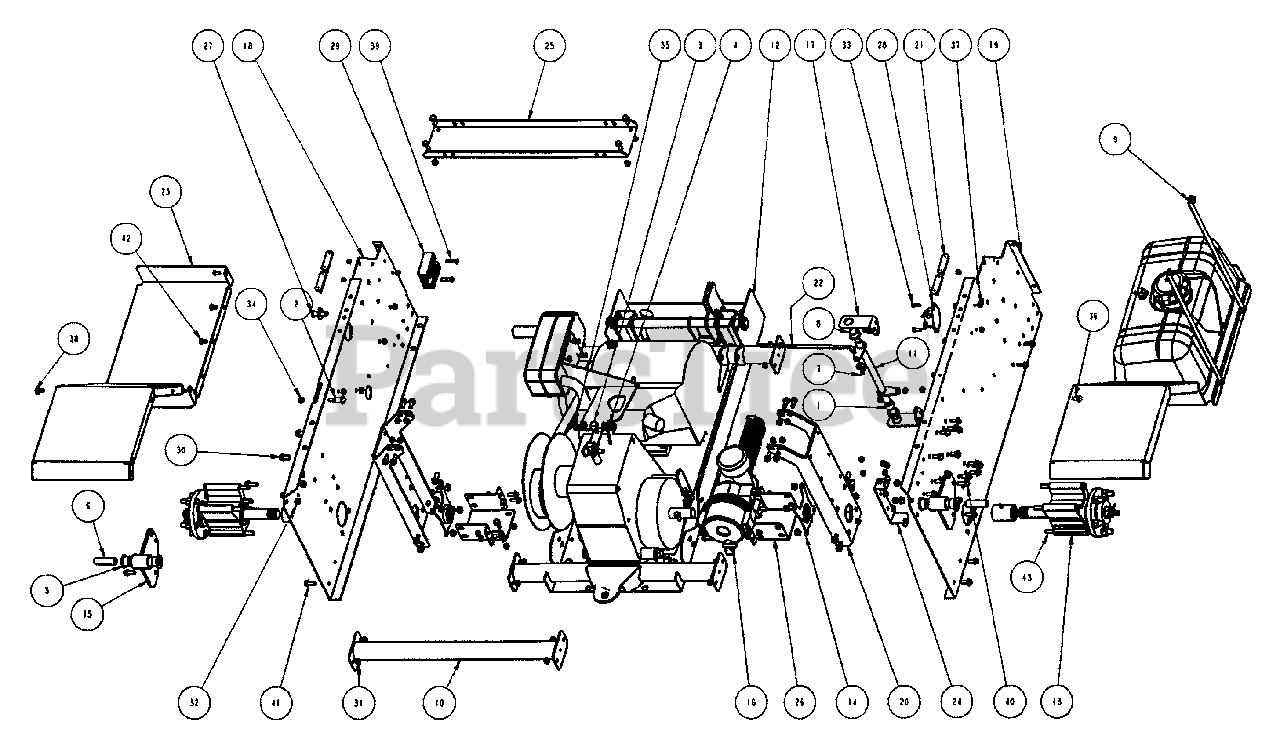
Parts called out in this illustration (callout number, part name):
1	RING, REAR LIFT ARM
2	HSB, 3/8-24 X 1-1/2
3	SWIVEL (3/8" THRU HOLE)
4	FRICTION PACK SPRING
5	BUSHING-SUSPENSION
6	SLEEVE-SUSPENSION
7	5/16 COTTER PIN, SELF LOCKING
8	BEARING, .750 ID
9	See "Fuel Tank Group" illustration and parts list
10	WELDMENT, TUBE SUPPORT
11	WELDMENT, SPEED CONTROL SHAFT
12	GROUP, DRIVE BASE
13	GROUP, CVT AXLE
14	ASSEMBLY, PLATE/SEAL
15	WELDMENT, DUMP BED PIVOT
16	AIR FILTER ASSEMBLY
17	BRKT., SPEED CONTROL X-SHAFT
18	FRAME, LH REAR
19	FRAME, RH REAR
20	STIFFENER, CVT FRAME
21	BUMPER, RUBBER
22	ROD, UPPER NEUTRAL RETURN
23	BRKT., GAS TANK
24	BRKT., AIR CLEANER MOUNTING
25	CHANNEL, FRAME STIFFENER
26	CHANNEL, SUBFRAME CONNECT
27	PIN, BED LATCH STRIKER
28	FUEL PUMP
29	REGULATOR/RECTIFIER, KAWASAKI
30	HWST, 3/8-16 X 3/4
31	HEX NYLON INSERT NUT 5/16-18 YZ
32	HNYL, 3/8-16, YZ
33	HHCS, 1/4-20 X 3/4 GR 5 YZ
34	HEX NYLOCK NUT 3/8-24
35	WASHER, .375 X.875 X.083
36	HFLB 3/8-16 X 3/4-YZ
37	1/4-20 HEX NYLON INSERT NUT
38	HFLB, 5/16-18 X .625-YZ
39	HHCS, 1/4-20 X 1.25 YZ
40	HFLB 3/8-16 X 1.0-YZ
41	HFLB, 5/16-18 x 7/8-YZ
42	RHSSNB, 5/16-18 x 5/8-YZ
43	HHCS, 3/8-16 X 5.5 - YZ
